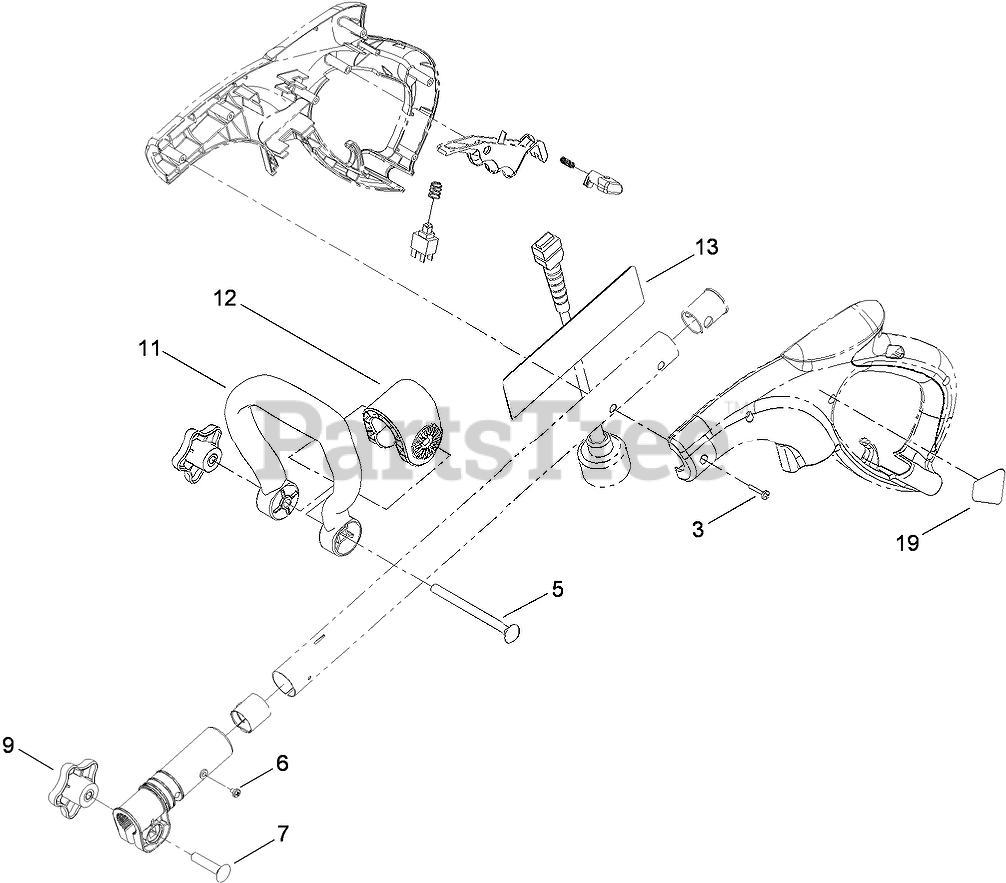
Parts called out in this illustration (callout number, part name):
3	SCREW-PPH
5	SCREW-CARR
6	SCREW-SELF TAPPING
7	BOLT-CARR
9	KNOB-HANDLE
11	HANDLE-ASSIST
12	COLLAR-HANDLE, ASSIST
13	DECAL-UL/WARNING
19	DECAL-CONTROL
